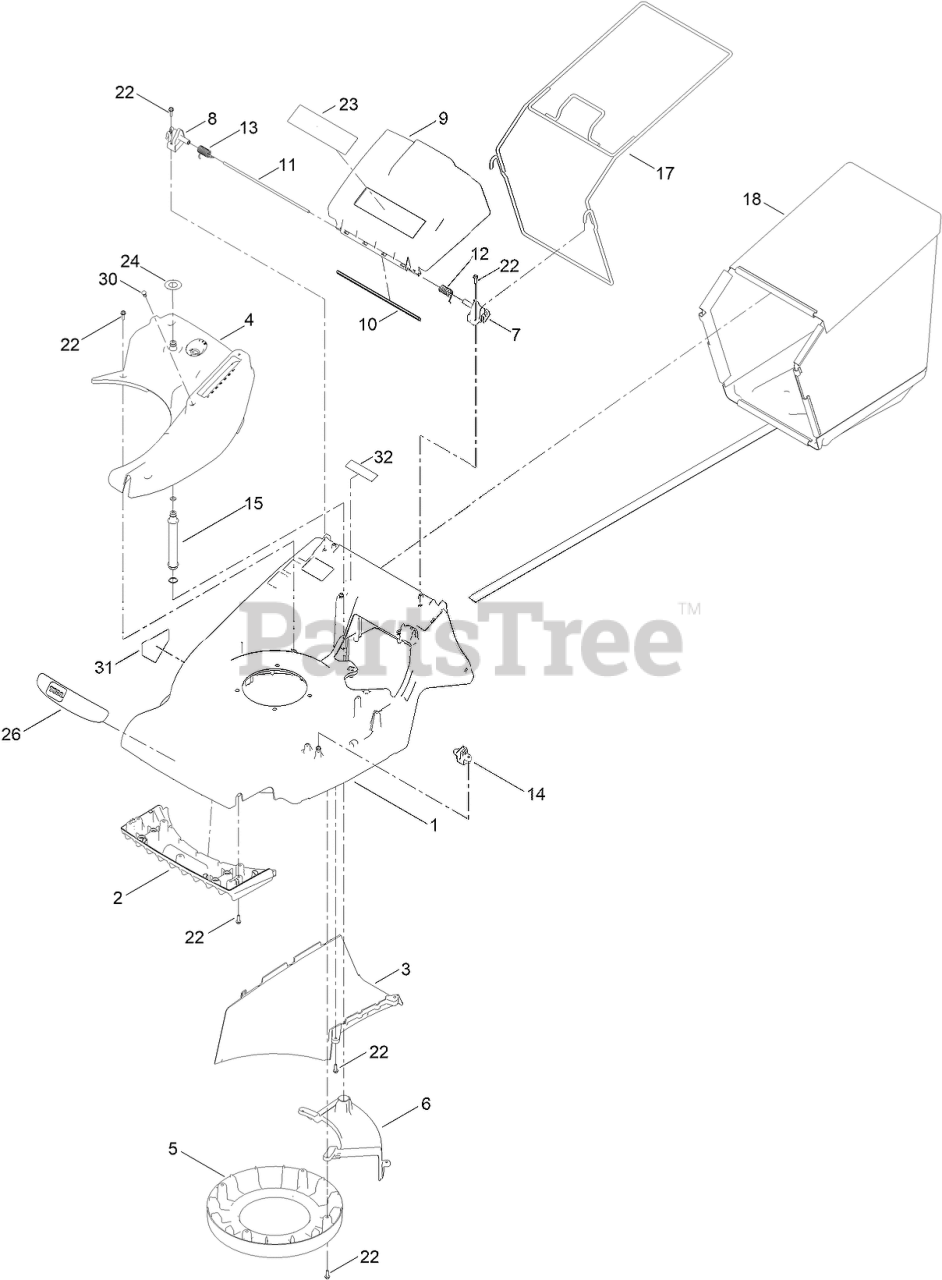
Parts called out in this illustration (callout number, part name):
1	HARRIER DECK ASSEMBLY
2	FINS-FRONT
3	PLATE-THROW
4	TRIM-TOP
5	COVER-BELT
6	COVER-BELT
7	MOUNT-DEFLECTOR, LEFT
8	DEFLECTOR MOUNT RIGHT
9	DEFLECTOR-REAR
10	DEFLECTOR-SEAL, REAR
11	ROD-DEFLECTOR
12	SPRING-DEFLECTOR, LEFT
13	SPRING-DEFLECTOR, RIGHT
14	ROD-SUPPORT
15	WASHPORT ADAPTER ASSEMBLY
17	GRASSBAG-FRAME
18	GRASSBAG-FABRIC, TORO
22	SCREW-TAPTITE
23	DECAL-SAFETY
24	DECAL-QUICK WASH
26	DECAL-PROSTRIPE 560
30	RIVET-PUSH, PLASTIC
31	DECAL-DANGER
32	DECAL-ARRESTOR, SPARK
